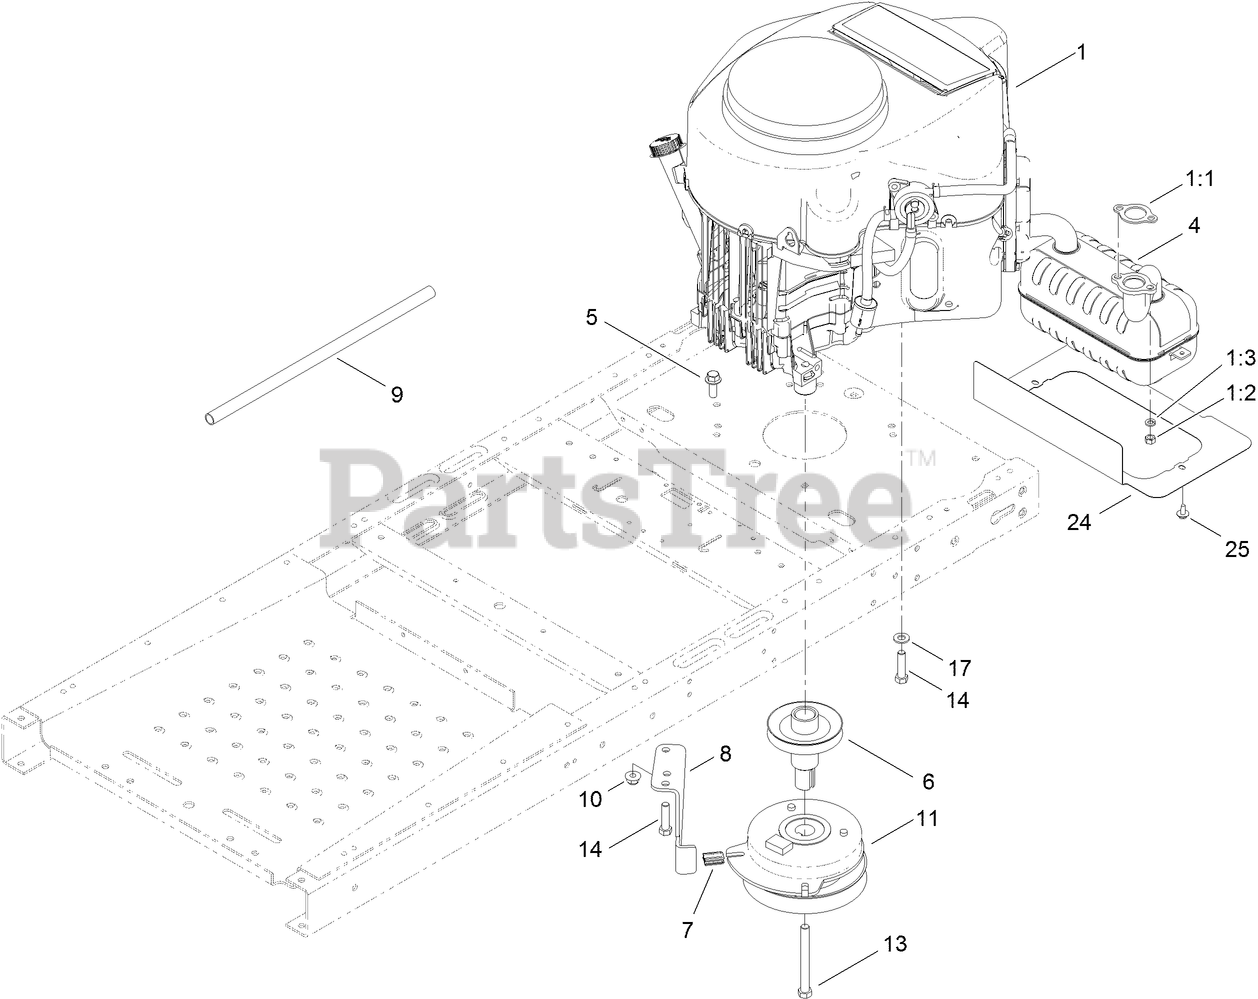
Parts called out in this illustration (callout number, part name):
1:1	GASKET-EXHAUST
1:3	WASHER-LOCK
4	MUFFLER-KAWASAKI
5	SCREW-HHF
6	PULLEY-ENGINE
7	ISOLATOR-CLUTCH
8	STOP-CLUTCH
9	TUBE-DRAIN, OIL
10	NUT-HF, NI
11	CLUTCH-ELECTRIC, PTO
13	SCREW-HH
14	BOLT-HH
17	WASHER-FLAT
25	SCREW-HHFTF
